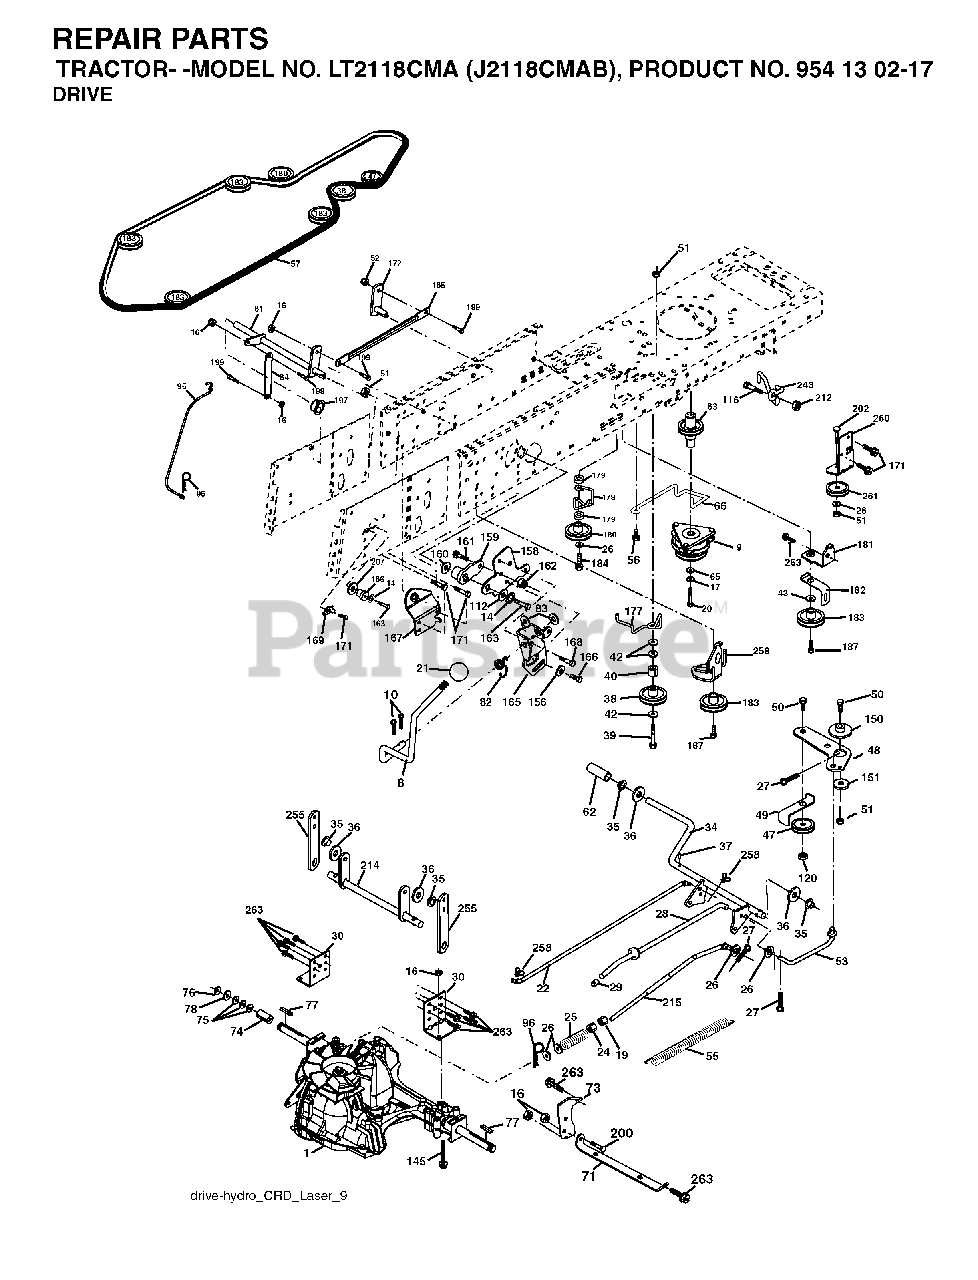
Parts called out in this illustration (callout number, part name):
8	ROD SHIFT
10	PIN COTTER
14	LOCKWASHER
16	NUT.71038.31-18.HEX.NYLOCK
17	LOCKWASHER
19	NUT
20	BOLT HEX 7/16-20X4-1/4"
21	PISTOL KNOB
24	NUT
25	SPRING ROD LT
27	COTTER PIN
28	ROD, PARKING BRAKE
29	PLUNGER CAP
30	BRKT, TRNSXLE MNT 20"
34	SHAFT, FOOT PEDAL
35	BEARING.NYLON
36	WASHER LT
37	DRIVE PIN
38	PULLEY.FLAT
42	WASHER
43	WASHER T
47	IDLER PULLEY
48	BELLCRANK, CLUTCH
49	RETAIN BELT
50	BOLT.3/8-16X1.50
51	LOCKNUT
52	LOCKNUT
53	LINK, CLUTCH LT
55	SPRING, RETURN LT
56	SCREW.3/8-16
62	PEDAL COVER T
66	KEEPER BELT ENGINE
71	STRAP TORQUE LH HYDRO
73	STRAP TORQUE RH HYDRO
74	SPACER AXLE
76	E-RING LT
77	SQUARE KEY
81	SHAFT ASSY
82	SHIFT SPRING
83	WASHER
96	RETAINER M
112	WASHER LT
116	BOLT D
120	NUT LOCK FLG 3/8-16 UNC
145	BOLT HEX 5/16-18 GR 5
150	BUSHING.BELLCRANK.GRD.DR
151	WASHER 12/32X2X10GA
156	WASHER.SRRTD.5/16
158	BRACKET
159	HUB.SHIFT
161	BOLT
162	NUT.CROWNLOCK.1/4
163	BOLT
165	RP BRACKET
166	SCREW
167	BRACKET
168	BOLT.SHOULDER.5/16-18X
169	PLATE.FASTENING.CROSS.SHAFT
171	SCREW LT
180	PULLEY.FLAT.IDLER
184	SCREW.HXWSH.3/8
187	BOLT.5/16-18X1.25
197	NYLINER SNAP 5/8" ID
199	BOLT SHOULDER 5/16-18 UNC
200	BOLT
202	BOLT
207	WASHER NYL
212	NUT
243	BRKT ASM MTNG
258	CLIP RETAINER
261	FLAT IDLER PULLEY
263	SCREW, 3/8-16X3/4
